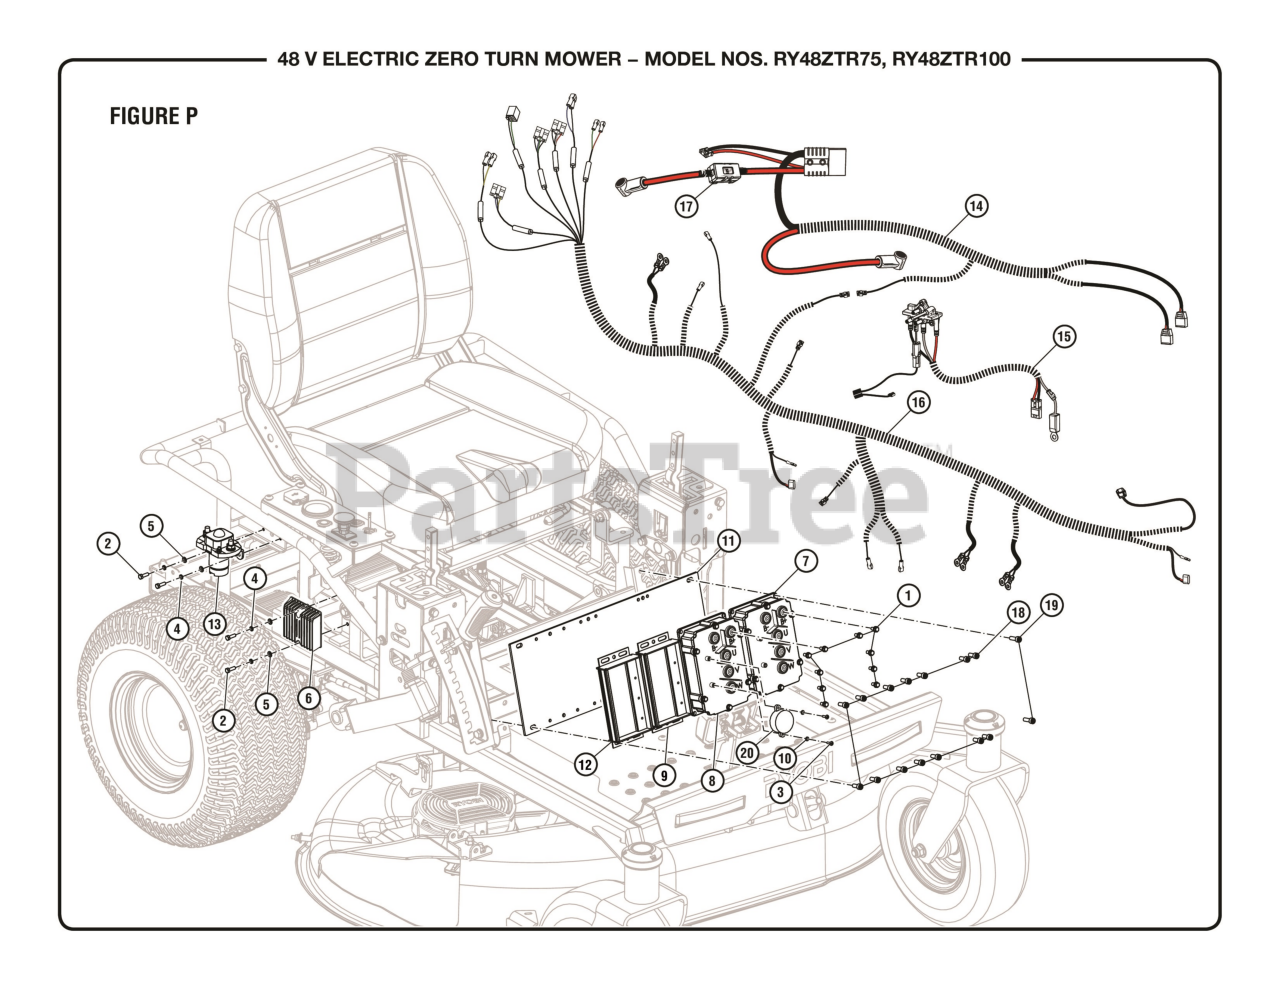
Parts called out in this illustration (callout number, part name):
1	Hex Flange Bolt (M5 x 12 mm)
2	Bolt (M5 x 16 mm, Hex hd.) (For Main Relay G)
3	Screw (M3 x 12 mm, Pan Hd.)
4	Lock Washer (For Main Relay G)
5	Washer (OD12 x ID5.3 x 1t) (For Main Relay G and Power Converter I)
6	DC to DC Converter, ZTR
7	Drive Motor Controller, Slave, ZTR
8	Drive Motor Controller, Master, ZTR
9	Deck Motor Controller, Master, ZTR
10	Washer (OD7 x ID3.2 x 0.6t) (For Beeper Q)
11	Controller Mounting Plate
12	Deck Motor Controller, Slave, ZTR
13	Main Relay (G)
14	Battery Output Cable
15	Charging Controller, ZTR
16	Main Wiring Harness
17	Fuse, 125 Amp
18	Screw (M6 x 16 mm, Soc. Hd.)
19	Screw (M6 x 20 mm, Soc. Hd.)
20	Beeper, ZTR
